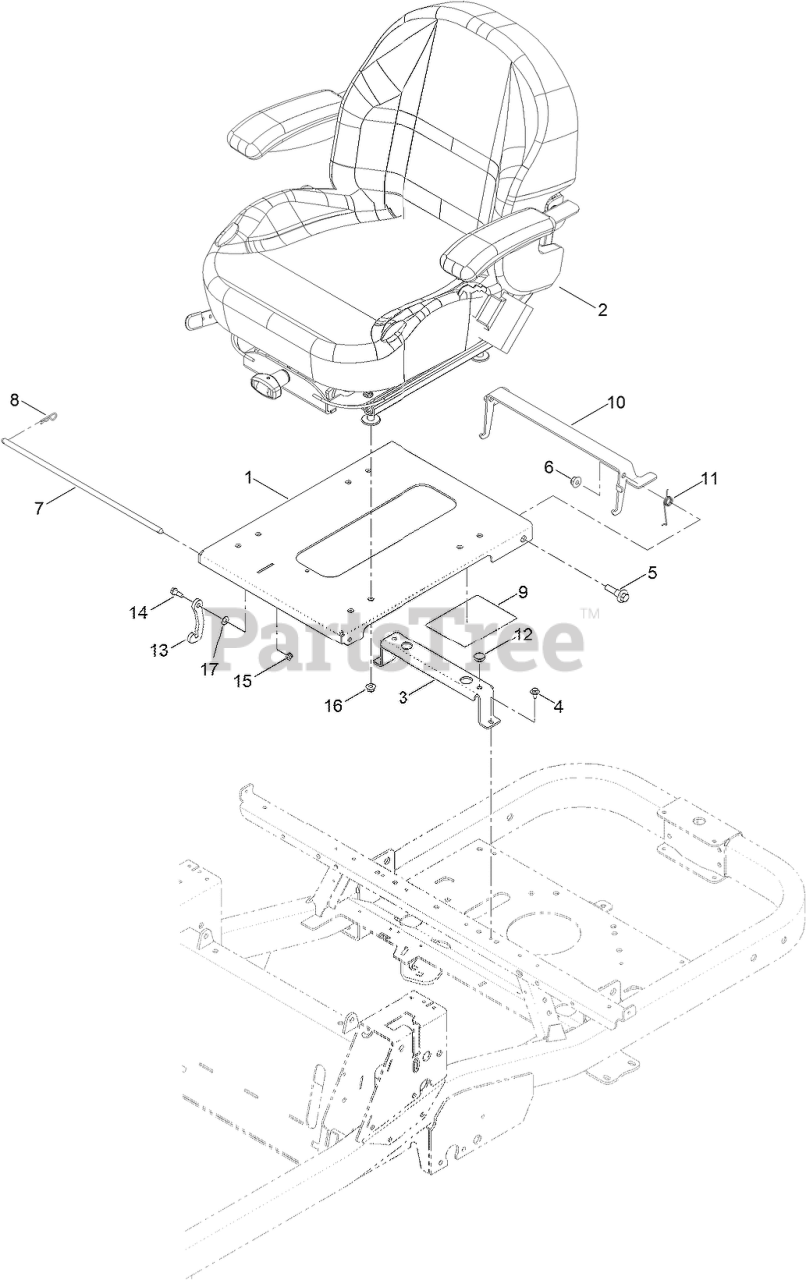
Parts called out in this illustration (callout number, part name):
1	SEAT PAN ASM
2	SEAT ASM
3	SEAT-SUPPORT, REAR
4	SCREW-HHFTF
5	BOLT-SHOULDER
6	NUT-HF, NI
7	ROD-STOP
8	PIN-COTTER
9	DECAL-MAINTENANCE
10	LATCH-SEAT
11	TORSION-SPRING
12	BUMPER
13	STOP-SEAT
14	BOLT-SHOULDER
15	NUT-LOCK, NI
16	NUT-HF, NI
17	WASHER
